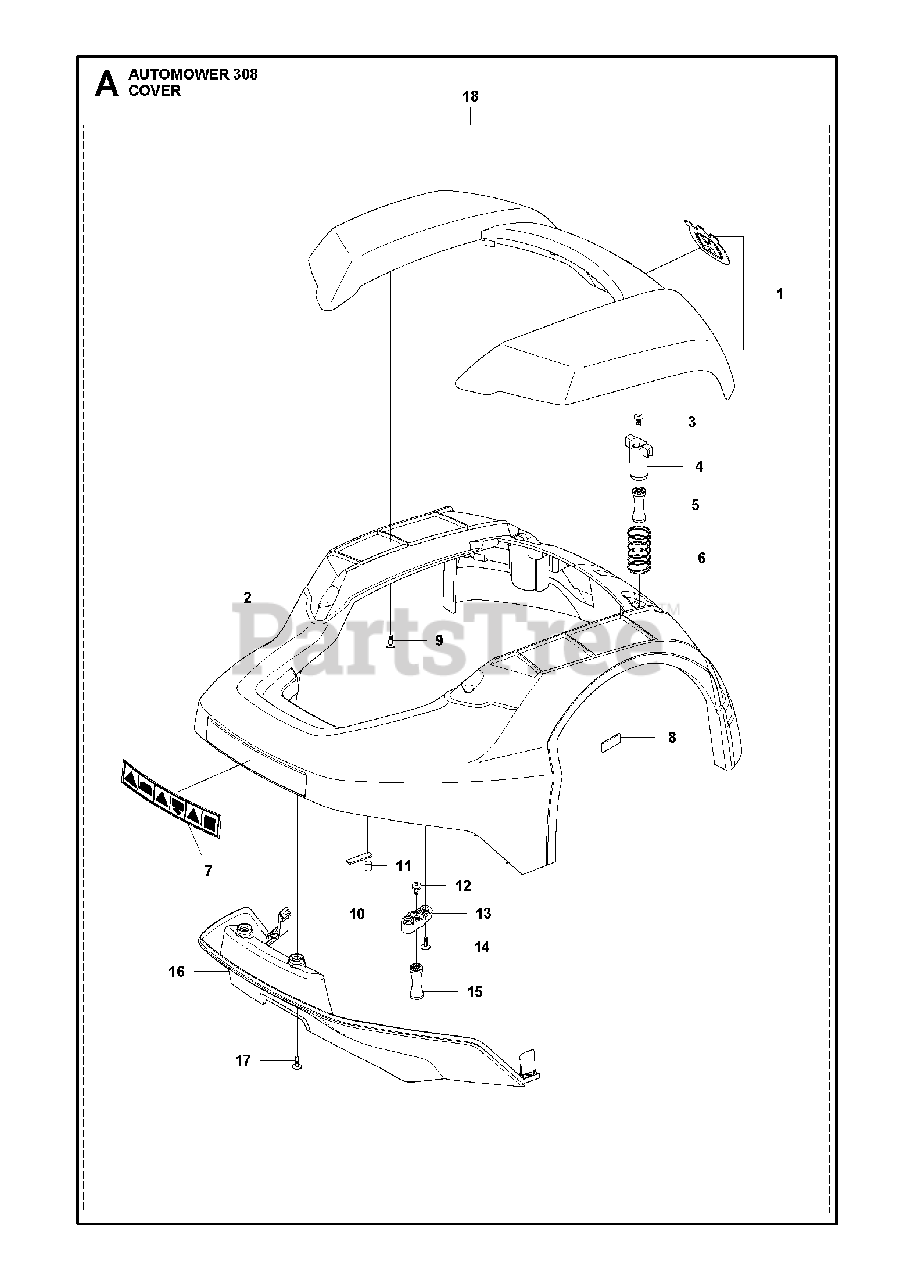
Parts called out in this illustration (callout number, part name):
3	SCREW ITXPANM M5X12 8
4	BRACKET COLUMN FRONT
5	DAMPER RUBBER 40 SHOR
6	SPRING LIFT SENSOR L
8	MAGNET LIFT SENSOR
9	SCREW 14MM
10	PLATE CARRIER MAGNET
11	MAGNET COLLISION SENS
12	SCREW ITXPANM M5X12 8
13	SUPPORT CLAMP USE WIT
14	SCREW 14MM
15	DAMPER RUBBER 40 SHOR
17	SCREW 14MM
